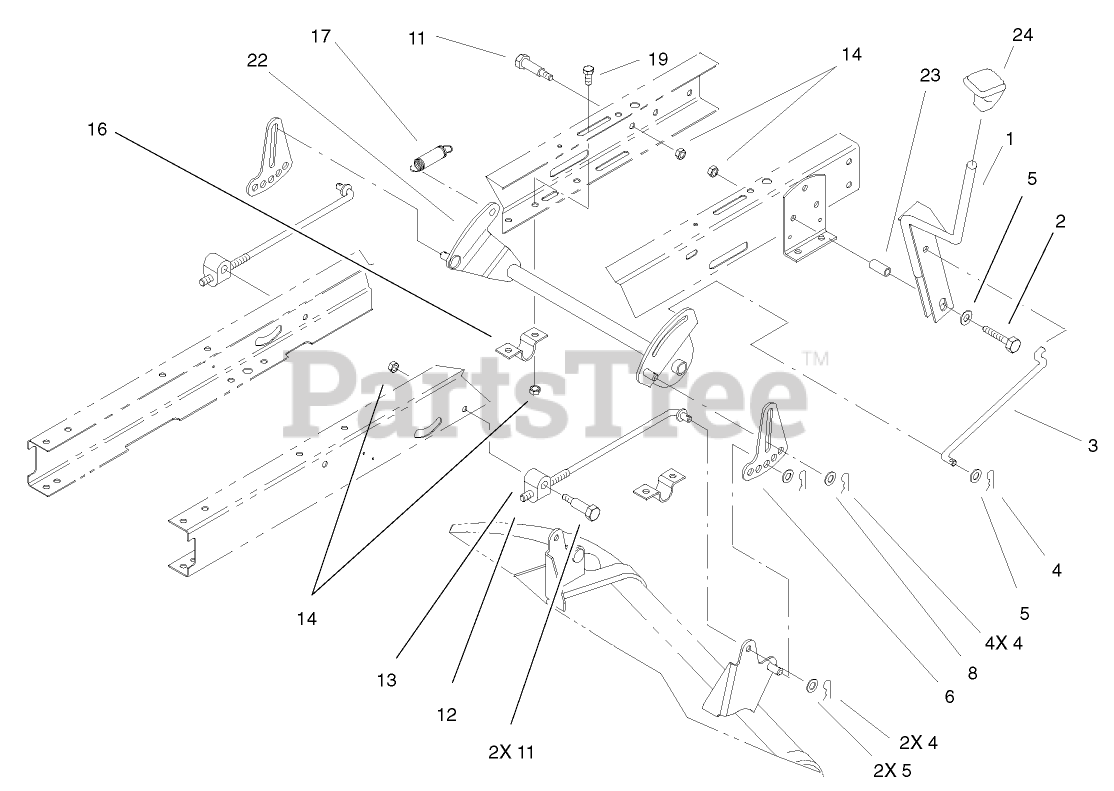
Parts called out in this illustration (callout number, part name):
2	SCREW-HH
3	LINK-HOC
5	WASHER-FLAT
6	LINK-ADJUSTING, HOC
8	WASHER-HARDENED
11	SCREW-SHOULDER, HH
12	ROD-HANGER, REAR
13	TRUNNION-HOC
14	NUT-LOCK, NI
16	CLAMP-PIVOT, HOC
17	SPRING-EXTENSION
19	SCREW-HH
22	PIVOT ASM
23	SPACER
24	KNOB-SHIFT
